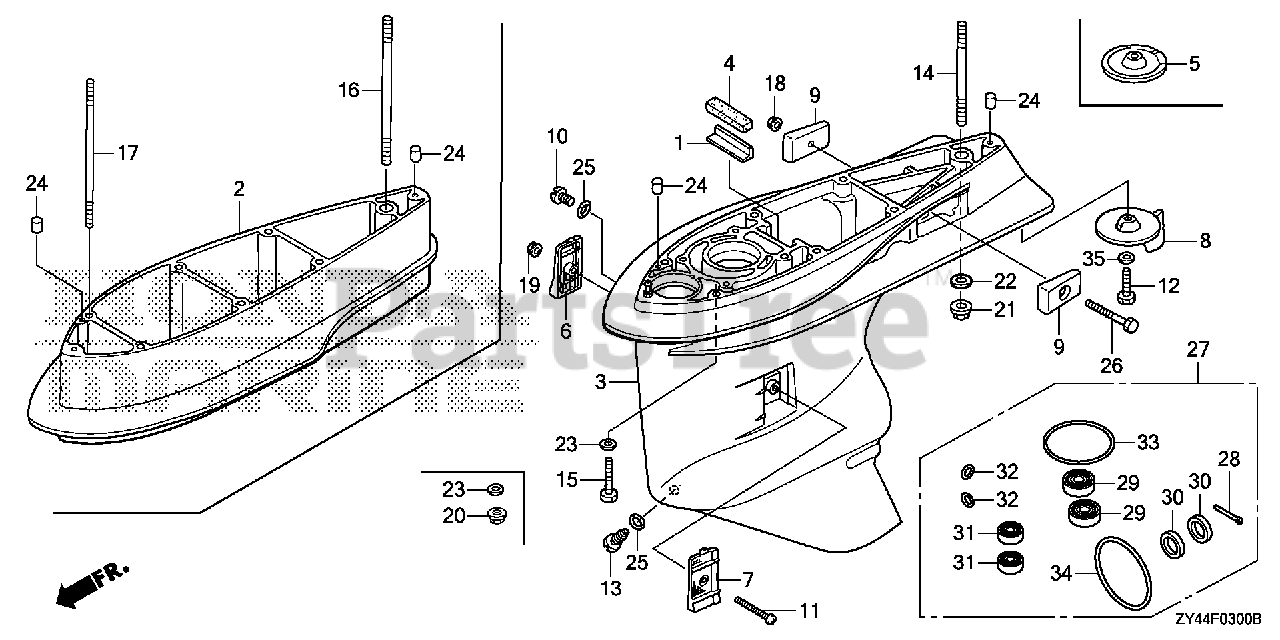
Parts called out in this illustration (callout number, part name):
1	PLATE, RUBBER SETTING
2	SEPARATOR, EXTENSION *NH282MU* (OYSTER SILVER METALLIC-U)
3	CASE, GEAR *NH282MU* (OYSTER SILVER METALLIC-U)
4	GROMMET, GEAR CASE
6	SCREEN, R. WATER
7	SCREEN, L. WATER
8	TAB, TRIM *NH282MU* (OYSTER SILVER METALLIC-U)
9	METAL, ANODE
10	BOLT, OIL CHECK
11	SCREW, FLAT (5X55)
12	BOLT, HEX. (10X32)
13	BOLT, DRAIN PLUG
16	BOLT, STUD (12X170)
17	BOLT, STUD (10X170)
18	NUT, SELF-LOCK (6MM)
19	NUT, SELF-LOCK (5MM)
20	NUT, SELF-LOCK (10MM)
21	NUT, SELF-LOCK (12MM)
22	WASHER, PLAIN (12MM)
23	WASHER, PLAIN (10MM)
24	PIN, DOWEL (6X10)
25	O-RING (6.9X1.45)
26	BOLT, HEX. (6X55)
27	CASE KIT, GEAR
28	PIN, SPLIT (4.0)
29	SEAL, WATER (26X42X7)
30	SEAL, WATER (30X45X7)
31	SEAL, WATER (12X21X6)
32	O-RING (6.9X1.45)
34	O-RING (110X3.1)
35	WASHER, PLAIN (10MM)
